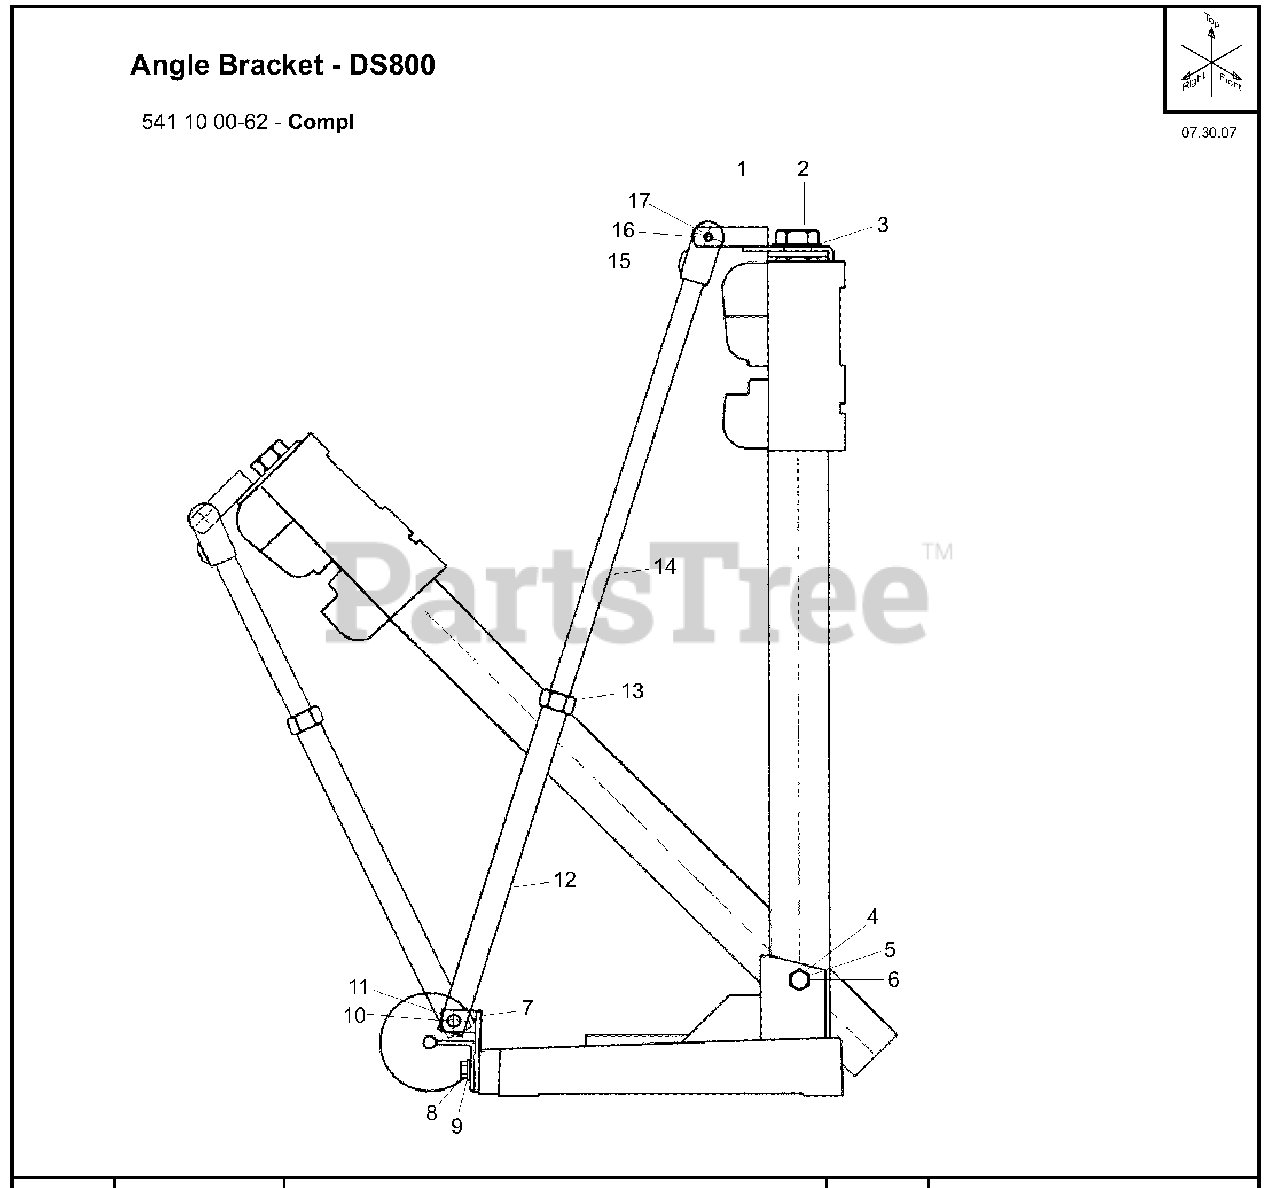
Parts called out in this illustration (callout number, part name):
1	Bracket, Upper Backstay - DS800
2	Capscrew, Hex Hd, 1-1/4" - 7 x 1-1/2
3	Washer, Flat 1-1/4 SAE
4	Washer, Flat 5/8 SAE
5	Locknut, 5/8-11 Thin Flexloc
6	Capscrew, Hex Hd, 5/8-11 x 4-1/4
7	Bracket, Lower Backstay
8	Capscrew, Hex Hd, 1/2-13 x 1-1/4
9	Washer, Flat 1/2 SAE
10	Capscrew, Hex Hd, 5/8-11 x 2-1/2
11	Locknut, 5/8-11 Thin Flexloc
12	Backstay, Lower
13	Nut, Jam - Backstay
14	Backstay, Upper
15	Adapter, Upper Bracket Rod
16	Capscrew, Hex Hd, 3/8-16 x 1-1/2
17	Locknut, Fiber 3/8-16
